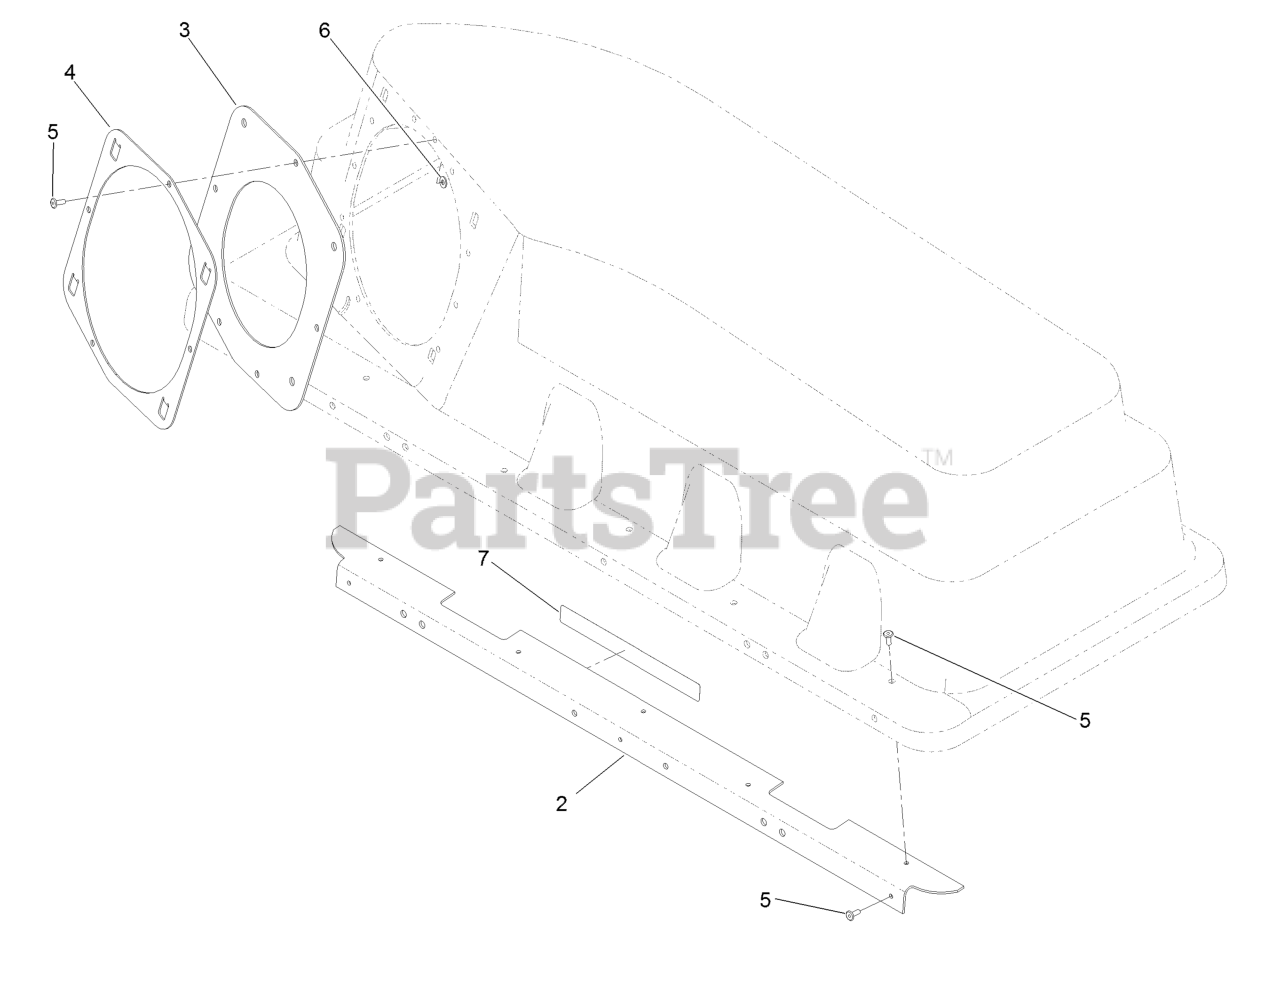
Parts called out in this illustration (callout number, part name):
2	Stiffener-Bagger Top
4	Ring-Retainer
5	Rivet-Blind
6	Washer-Flat
7	Decal-Caution, Bagger
